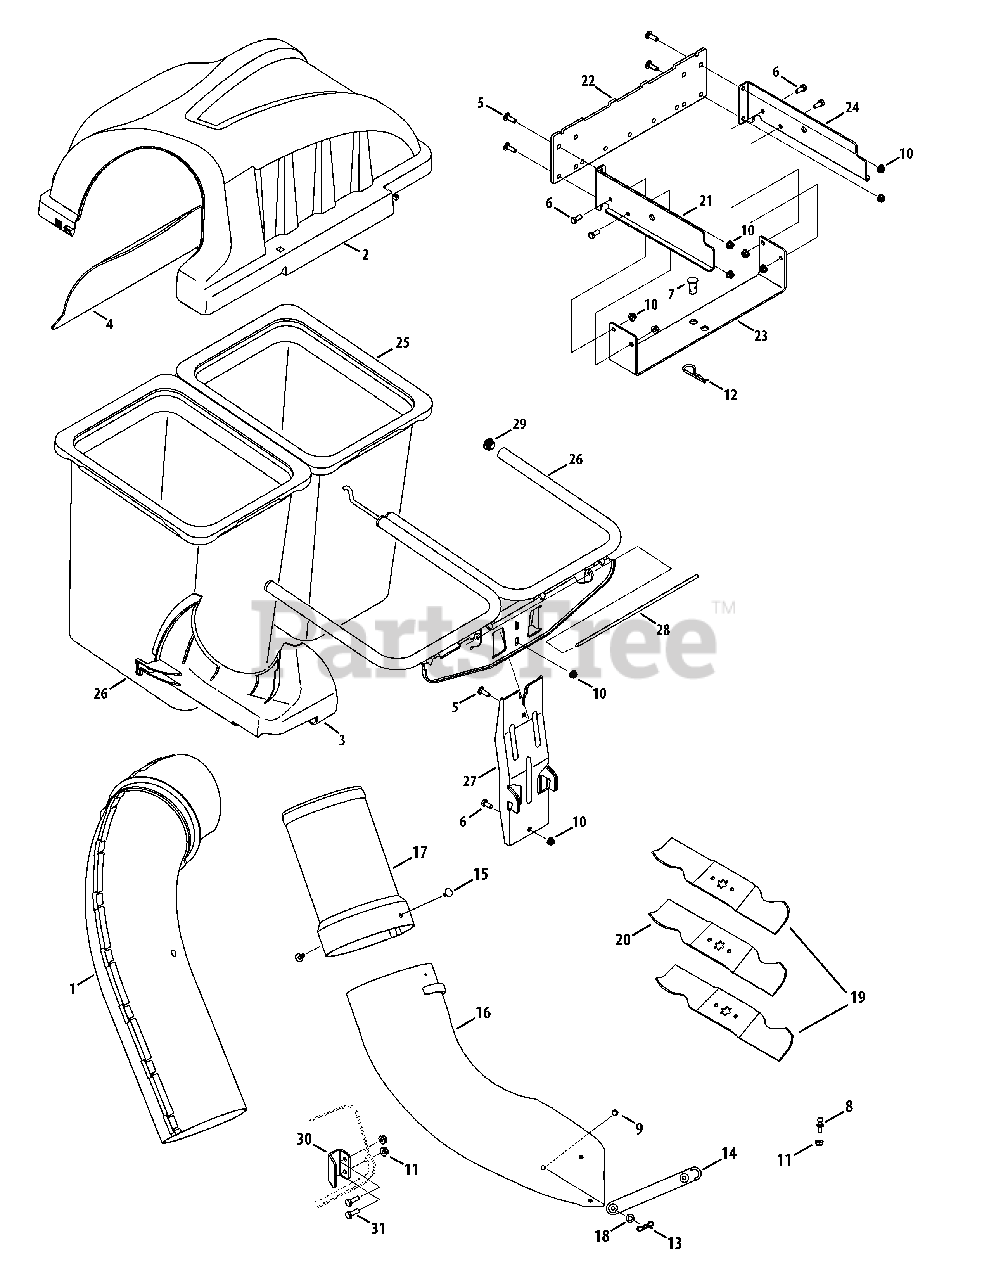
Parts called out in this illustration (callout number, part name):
1	Upper Chute Assembly
2	Double Bagger Cover Assembly
3	Upper Chute Support
4	Bagger Cover Screen
5	Carriage Screw, 5/16-18 x 1.00"
6	Hex Head Screw, 5/16-18 x .75"
7	Clevis Pin, .62" Dia.
8	Grass-catcher Pin, 1/4-20
9	Clevis Pin, 5/16 x .75 Lg.
10	Flange Lock Nut, 5/16-18
11	Flange Lock Nut, 1/4-20
12	Internal Cotter Pin, .148 x 3.00
13	Bow-Tie Cotter Pin, 72
14	Chute Strap, 6.00 Lg.
15	Ratchet Clip
16	Bagger Discharge Chute, Elbow
17	Bagger Chute Adapter
18	Flat Washer, .344 x .62 x .033
19	Blade, 16.28 Lg. Star 2-in-1
20	Blade, 14.88 Lg. Star 2-in-1
21	Mounting Bracket, RH
22	Universal Mounting Bracket
23	Universal Bracket Support, I-Series
24	Mounting Bracket, LH
25	Grass-bag Assembly
28	Cover Hinge Pin
30	Chute Bracket
31	Hex Bolt, 1/4-20 x .75
